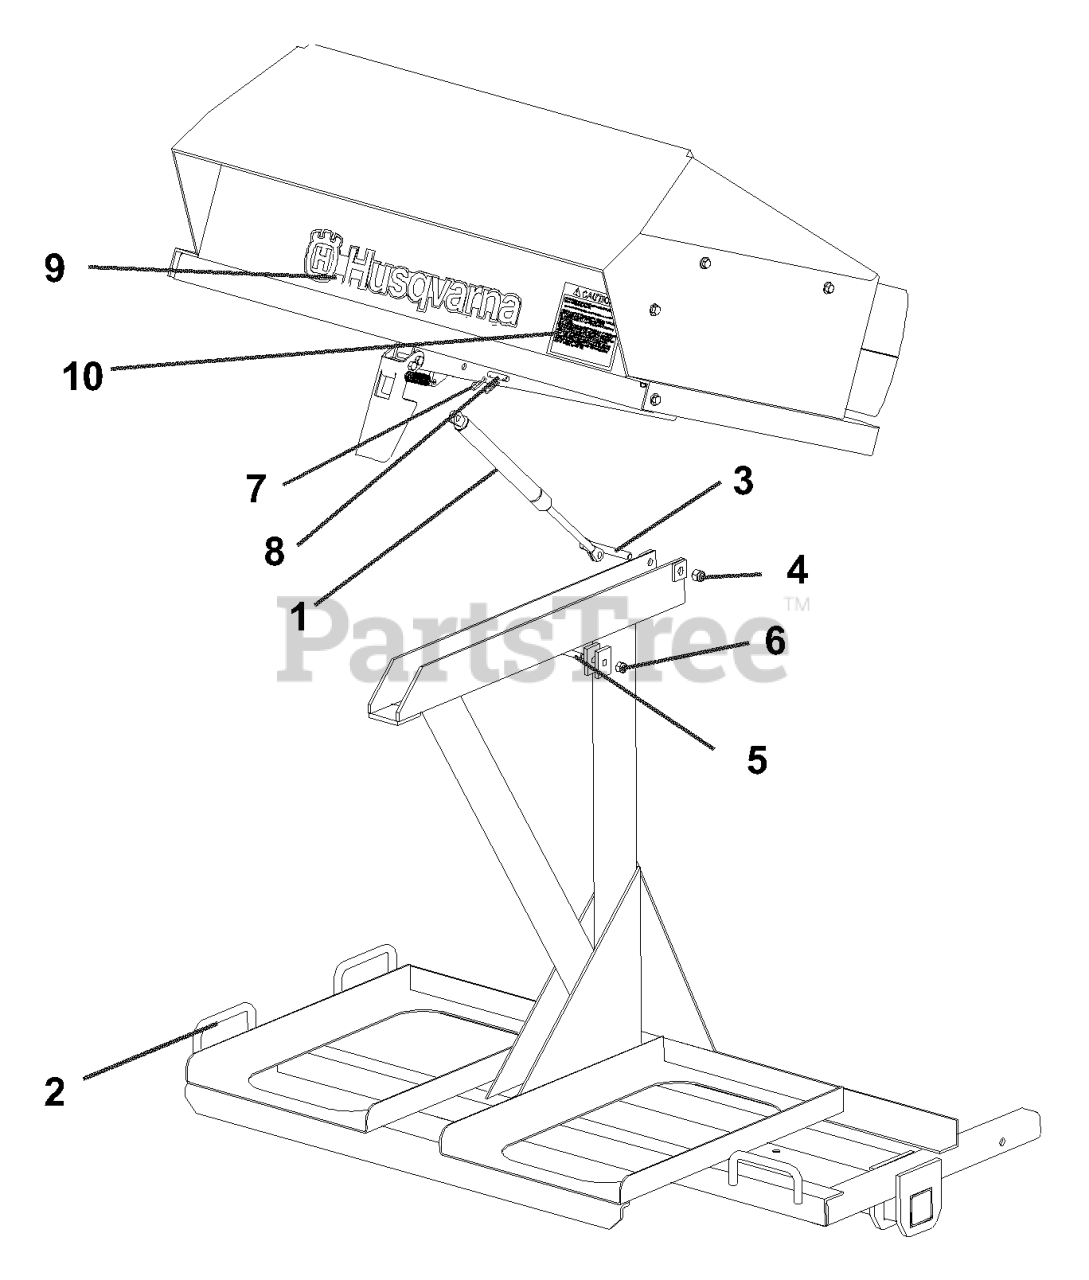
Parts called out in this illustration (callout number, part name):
1	GAS SPRING - CZ9
2	FRAME, BLACK
3	Bolt, Hex, 3/8"-16 x 3"
4	NUT 3/8 NYLOC
5	Bolt, Hex, 5/16"-18 x 1-1/2"
6	HEX NUT - NYLON LOCK 5/16-18
7	PIN, HAIR COTTER #13 5/64 X 1
8	Pin, Clevis, 5/16" x 1-1/4" w/ 2 holes
9	R/B 104804 DECAL HUSQ 2.94X15
10	DECAL, CAUTION LIST
